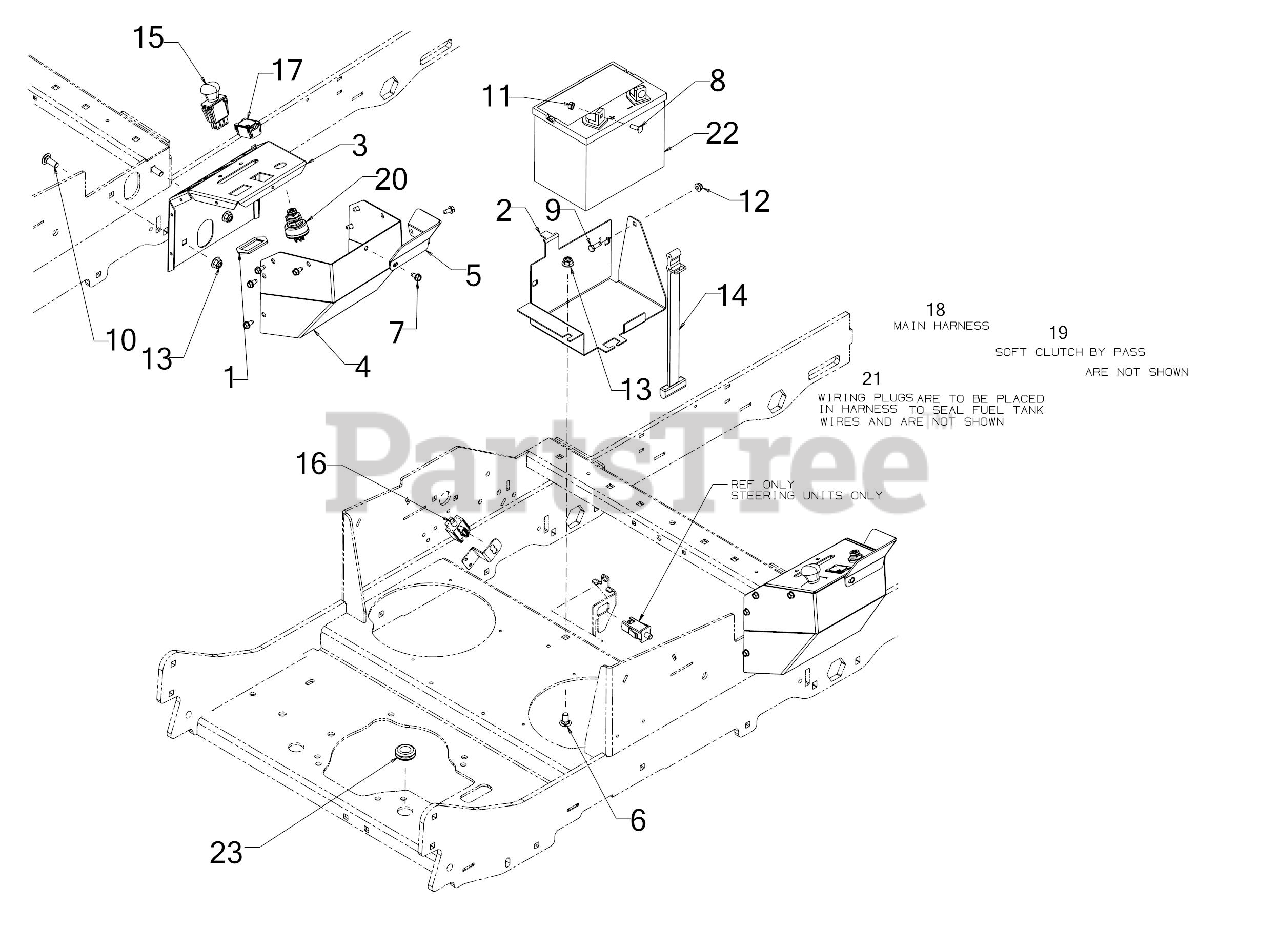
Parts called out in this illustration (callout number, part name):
1	BRACKET-PTO SWITCH
2	BATTERY MOUNTING BRACKET
3	CONTROL POD - (RH)
4	CONTROL POD COVER (RH)
5	THROTTLE DEFLECTOR
6	CARRIAGE BOLT 3/8-16 x .750 GR5
7	SCREW 1/4-20 X.500
8	SCREW 1/4-20 x .75 GR5
9	SCREW 1/4-20X.75 GR5
10	CARRIAGE BOLT 3/8-16 x 1.00 GR5
11	SEMS NUT 1/4-20
12	FLANGE LOCK NUT
14	BATTERY RETAINER STRAP
15	ELECTRIC PTO SWITCH
16	3 POLE SWITCH ( NC-NO-NO)
17	HOUR METER
18	WIRE HARNESS ASSEMBLY
19	BYPASS HARNESS
20	KEY SWITCH (3 POSITION)
21	SEALED CAP ASSEMBLY
23	RUBBER GROMMET
